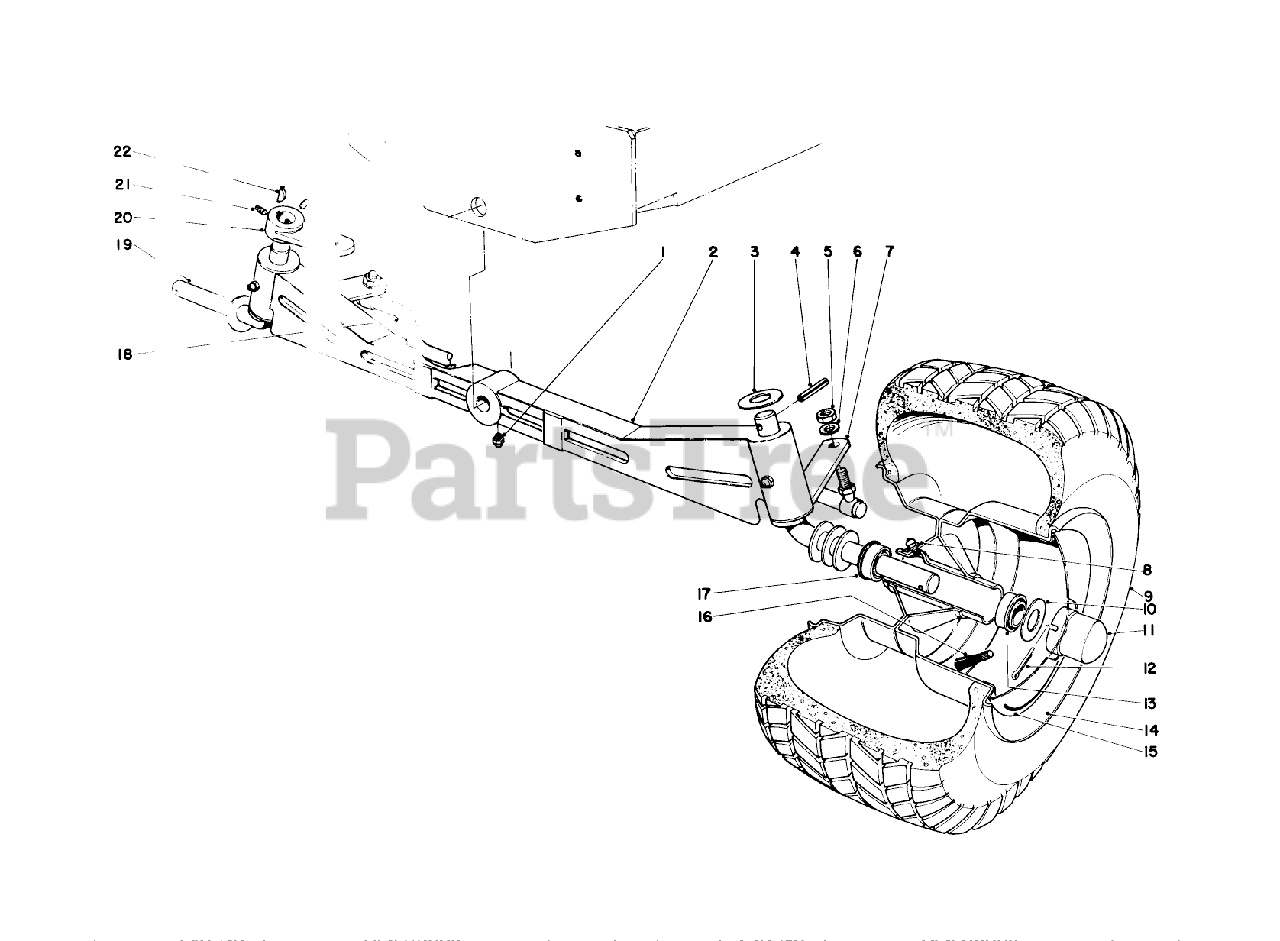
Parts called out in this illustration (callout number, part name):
1	Grease Fitting
3	WASHER-FLAT
4	PIN-ROLL
5	NUT-HEX
6	WASHER-LOCK
7	Axle Assy., L.H.
8	Grease Fitting
10	WASHER-FLAT
11	Hub Cap 10 H.P.
12	PIN-COTTER
15	Hub Cap 960
17	Bearing, Inner
18	Tie Rod
19	Axle Assy., R.H.
20	Steering Lever
21	SCREW-SQH
22	KEY-WOODRUFF
